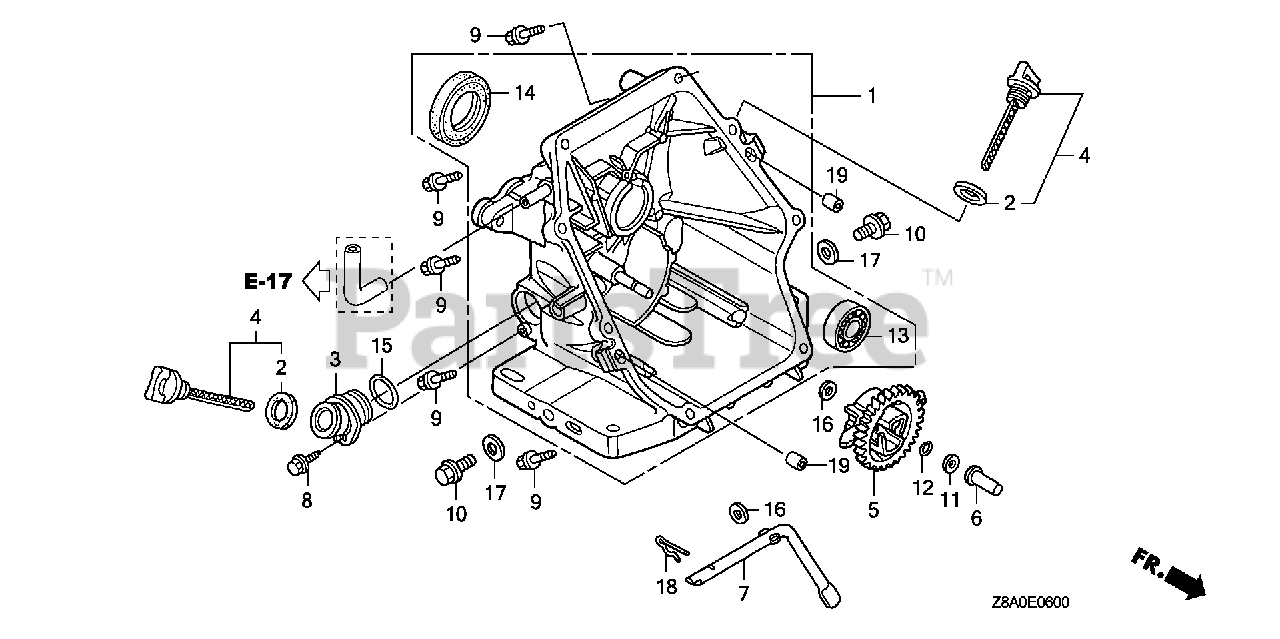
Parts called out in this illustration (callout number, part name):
1	COVER ASSY., CRANKCASE (U-TYPE)
2	GASKET, OIL FILLER CAP
4	GAUGE ASSY., OIL LEVEL
5	GOVERNOR ASSY.
6	SLIDER, GOVERNOR
7	SHAFT, GOVERNOR ARM
9	BOLT, FLANGE (6X25) (CT200)
10	BOLT, DRAIN PLUG (12X15)
11	WASHER, THRUST (6MM)
12	CLIP, GOVERNOR HOLDER
13	BEARING, RADIAL BALL (62/28)
14	OIL SEAL (28X41.25X6)
16	WASHER, PLAIN (6MM)
17	WASHER, DRAIN PLUG (12MM)
18	PIN, LOCK (8MM)
19	PIN, DOWEL (8X20)
